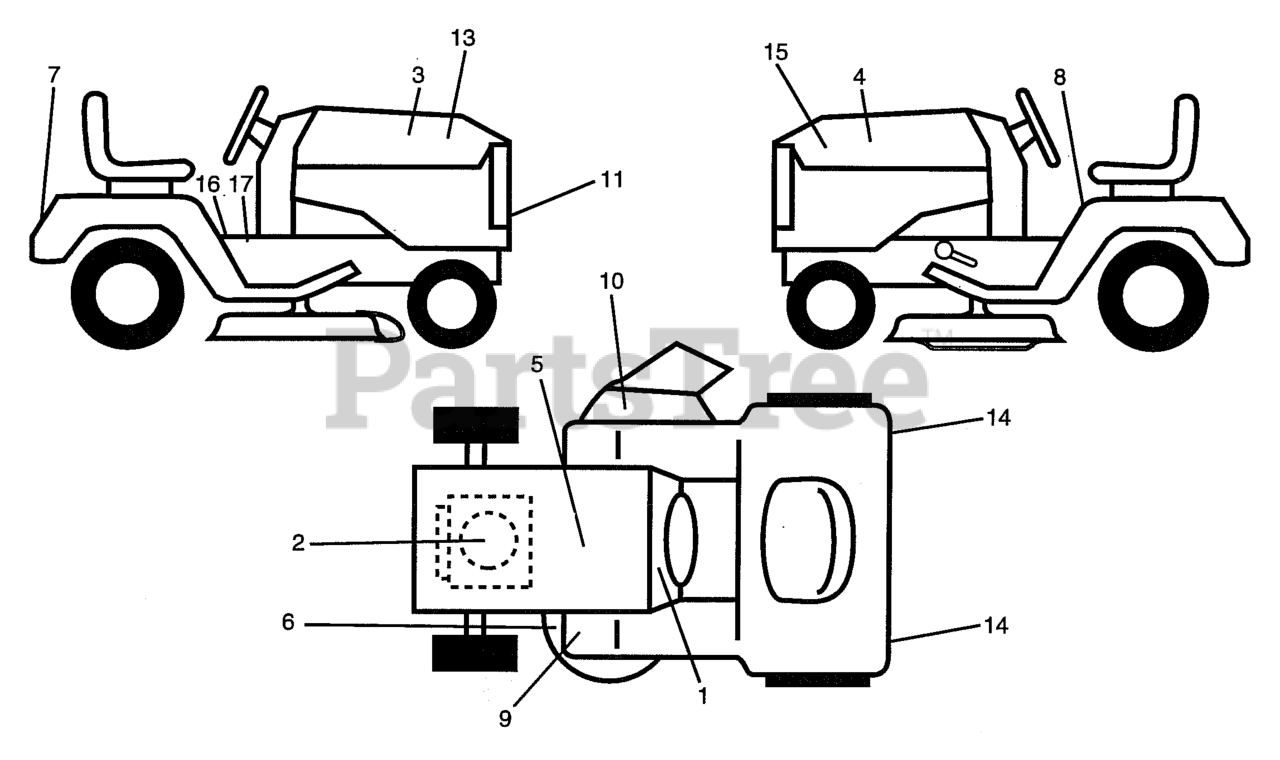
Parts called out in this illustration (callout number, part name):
2	DECAL ENGINE HP
7	DECAL FENDER NLA
8	DECAL CAUTION
10	DECAL WARNING (ENGLISH/FRENCH)
11	DECAL GRILL HUSQ NLA
13	DECAL-HOOD R.H.
14	REFLECTOR-TAIL YT
15	DECAL-HOOD L.H.
17	DECAL PARK BRAKE
